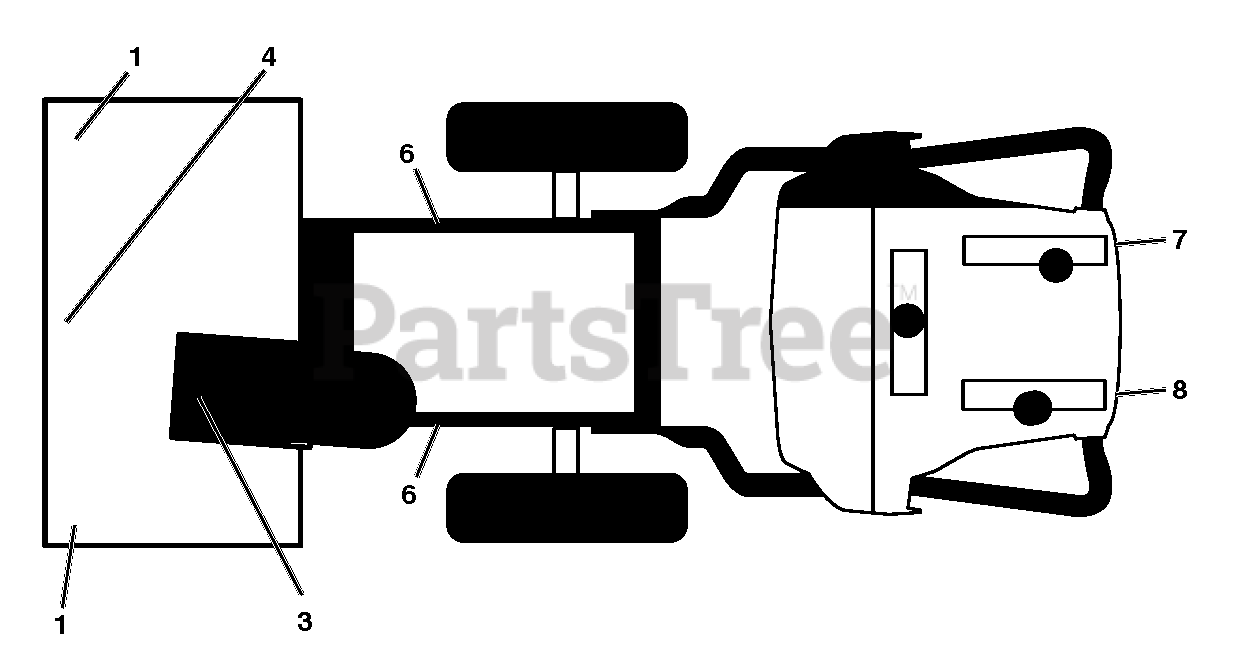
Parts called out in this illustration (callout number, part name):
1	DECAL.AUGER.SAFETY.
3	DECAL.CHUTE.SAFETY.
4	DECAL.AUGER."
6	DECAL.BELT.GUARD.
